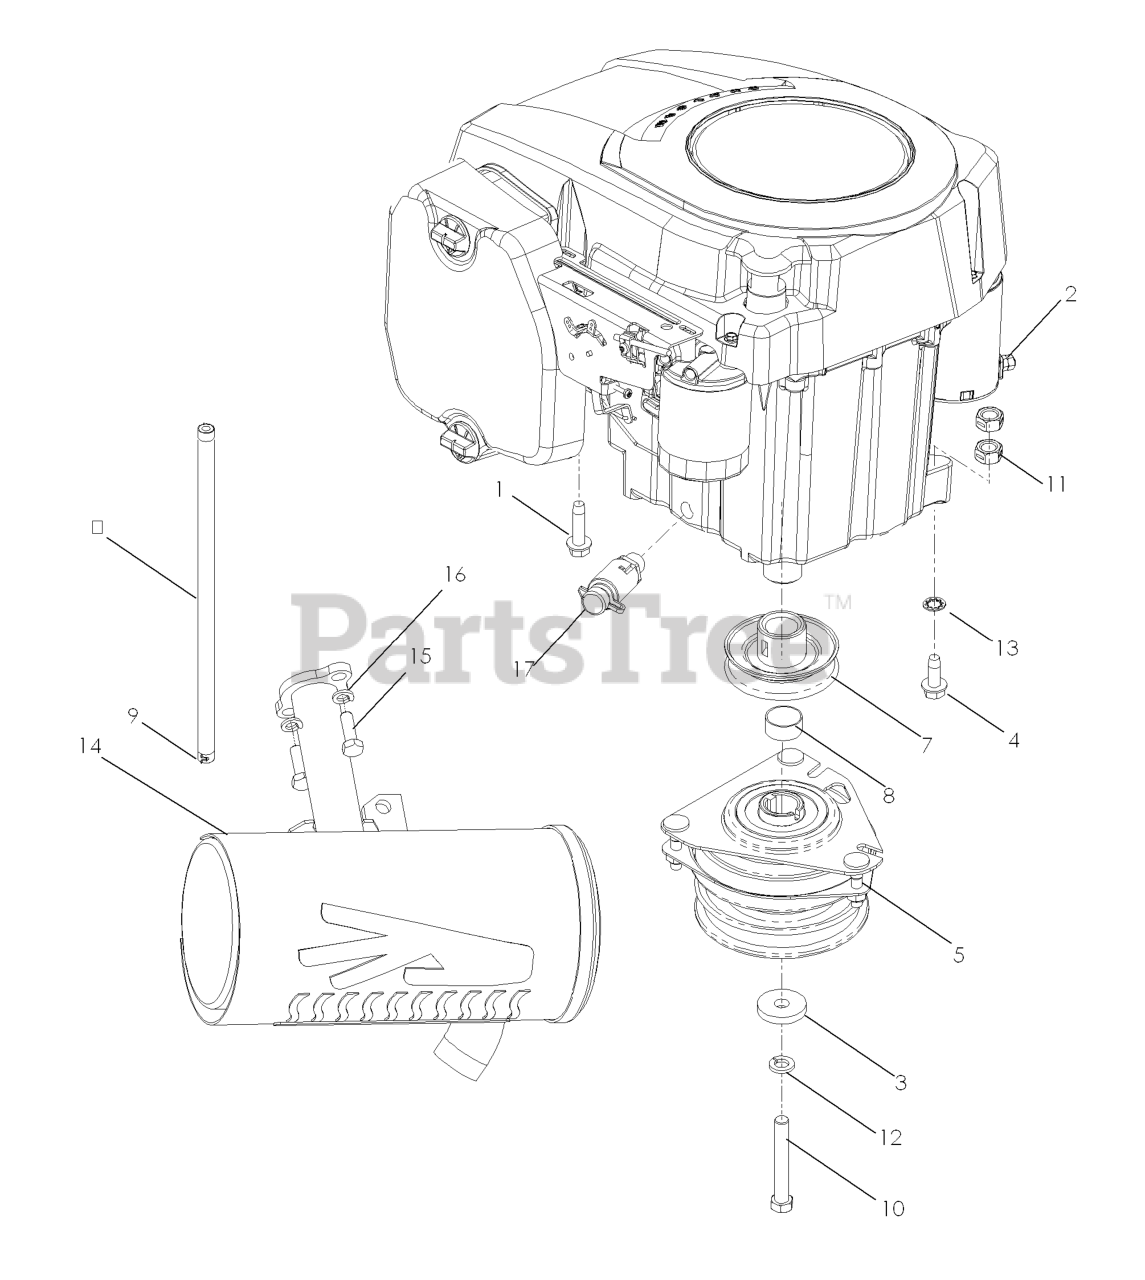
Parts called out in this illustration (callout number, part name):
1	BOLT 3/8-16 X 1.0
2	JAM NUT 1/4C (2 2 PW01)
3	CLUTCH, WASHER
5	CLUTCH 90 FT/LB OGURA
6	FUEL LINE 5"
7	PULLEY, ENGINE
8	SPACER, ENGINE - PULLEY
9	HOSE CLAMP
10	HEX SCREW 7/16-20 X 3
11	NUT 5/16C CENTERLOCK
12	WASHER 7/16 LOCK
13	WASHER, 3/8 ITLW ZN
15	HCS 5/16C X 1
16	WASHER.LOCK.HVY.HLCL.SPR.5/16
17	OIL DRAIN FITTING
